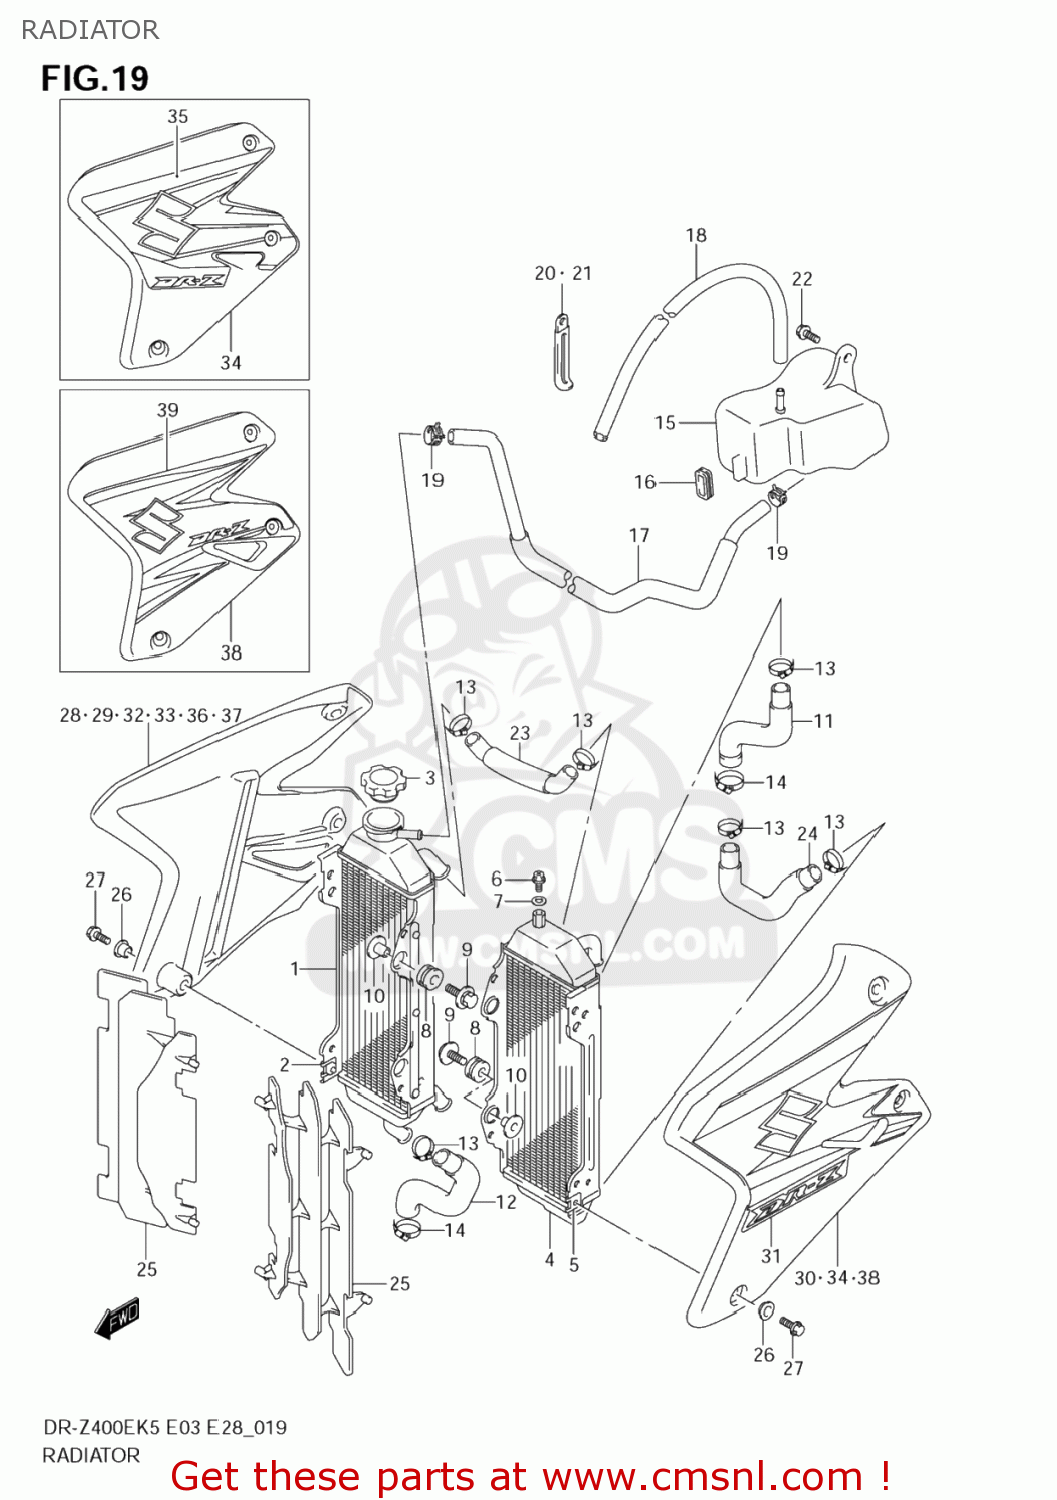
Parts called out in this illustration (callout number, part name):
1	RADIATOR,WATER,R
2	NUT
3	CAP,RADIATOR
4	RADIATOR,WATER,L
5	NUT
6	UNION BOLT,AIR VENT
7	GASKET(6.4X11.5X0.8) (NAS)
8	CUSHION,RADIATOR LWR
9	BOLT(6X25)
10	SPACER(6.5X10.5X14.1)
11	HOSE,RADIATOR INLET
12	HOSE,RADIATOR OUTLET
13	CLAMP
14	CLAMP
15	TANK,RESERVOIR
16	CUSHION,RESERVOIR TANK
17	HOSE,RESERVOIR TANK INLET
18	HOSE(5X9X2000)
19	CLIP
20	CLAMP(L:45 T:0.6)
21	CLAMP(L:45)
22	BOLT
23	HOSE,RADIATOR JOINT
24	HOSE,RADIATOR JOINT LWR
25	LOUVER,RADIATOR
26	WASHER
27	BOLT
28	COVER,RADIATOR,R(YELLOW)
29	TAPE,RADIATOR COVER,R
30	COVER,RADIATOR,L(YELLOW)
31	TAPE,RADIATOR COVER,L
32	COVER,RADIATOR,R(YELLOW)
33	TAPE,RADIATOR COVER,R
34	COVER,RADIATOR,L(YELLOW)
35	TAPE,RADIATOR COVER,L
36	COVER,RADIATOR,R(YELLOW)
37	TAPE,RADIATOR COVER,R
38	COVER,RADIATOR,L(YELLOW)
39	TAPE,RADIATOR COVER,L
